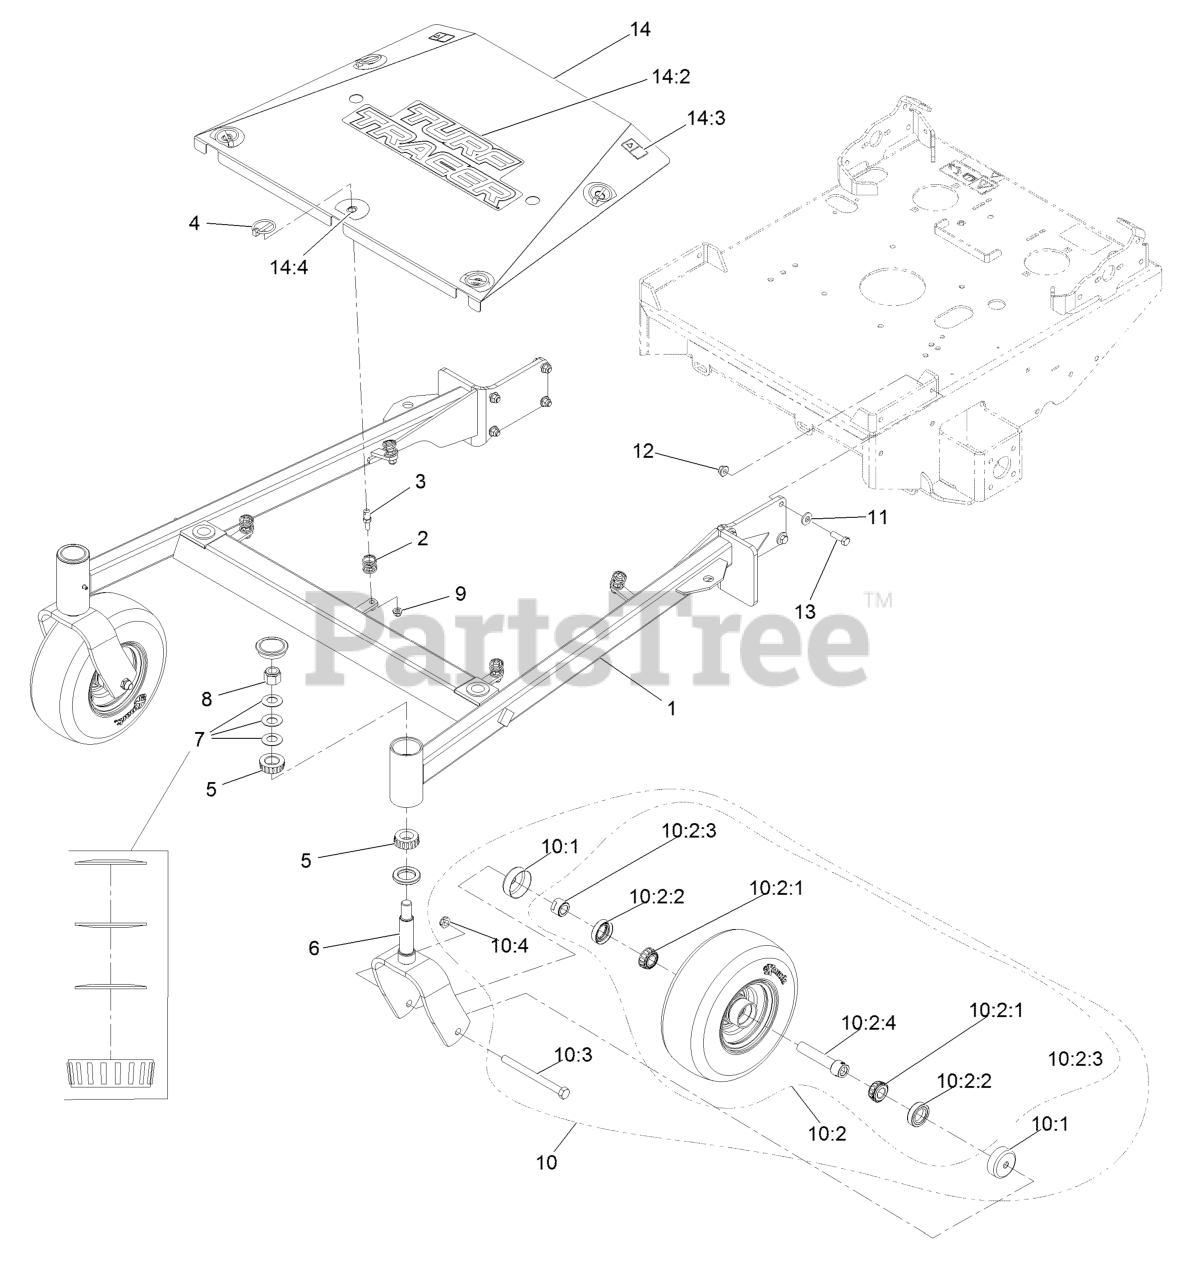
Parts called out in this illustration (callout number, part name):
1	ASM, FRONT FRAME W/ BEARI
3	PIN-SPRING
4	PIN-LYNCH
5	Cone-Bearing Tapered Roller
6	WLD, CASTER FORK
7	WASHER-BELLVILLE
8	NUT-LOCK, NI
9	NUT-HF, NI
10	ASM,WHEEL&BEARINGS
10:1	GUARD-SEAL
10:2	ASM,Wheel And Bearing
10:2:1	BEARING-CONE, TAPERED ROLLER
10:2:2	SEAL-CASTER
10:2:3	SPACER-NUT
10:2:4	CASTER AXLE ASM
10:3	SCREW-HH
10:4	NUT-HEX
11	WASHER-BELLEVILLE
12	NUT-HF, NI
13	SCREW-HH
14	ASM, CENTER SHIELD W/ DEC
14:2	DECAL-TURF TRACER
14:3	DECAL-WARNING
14:4	DECAL-SCRATCH COVER
